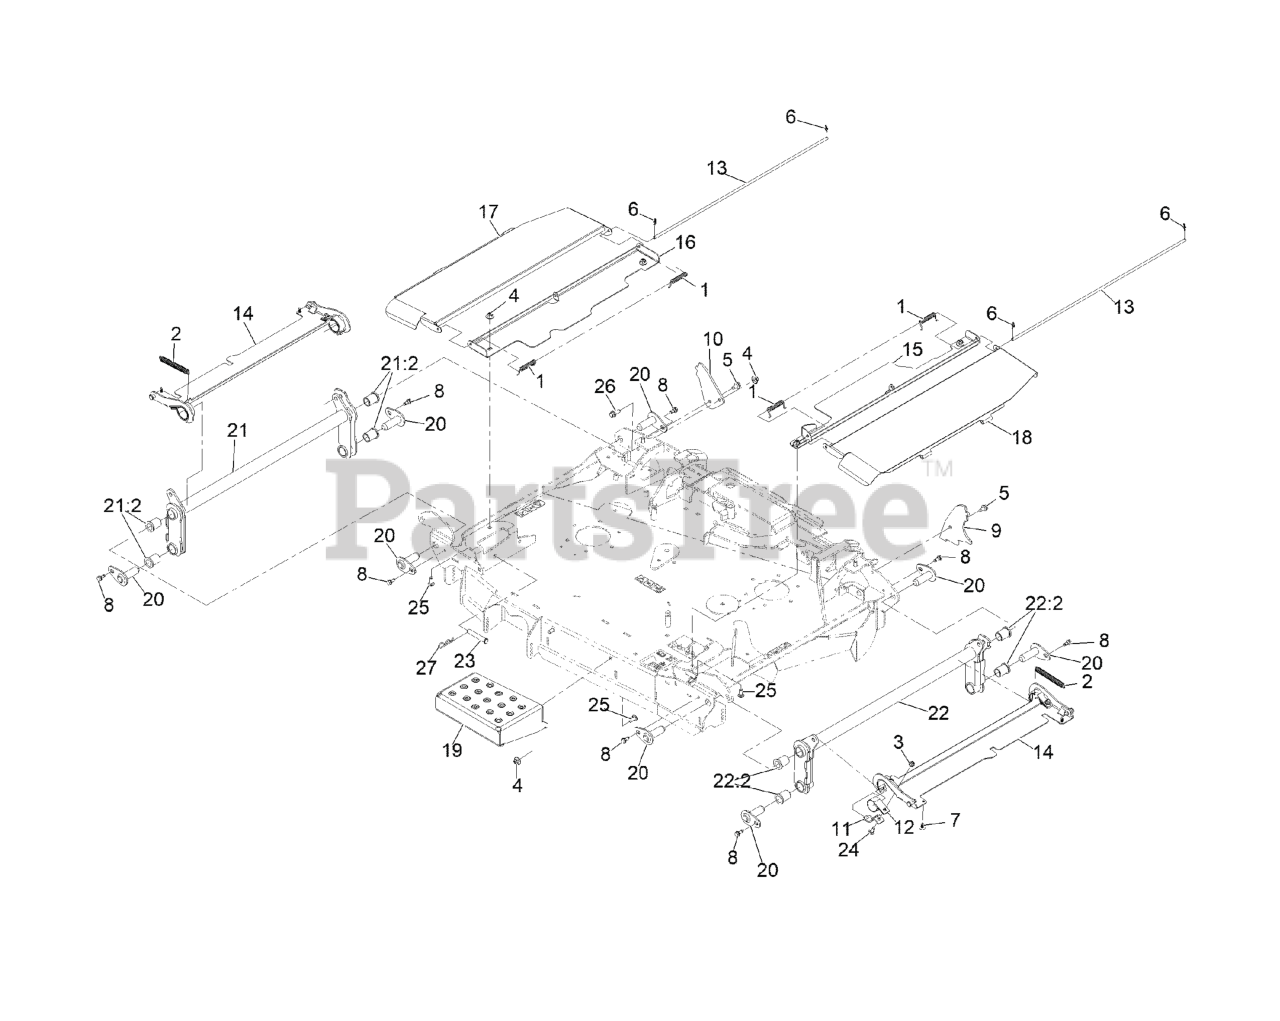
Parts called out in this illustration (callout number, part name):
1	SPRING-TORSION
3	NUT-HF, NI
4	Nut-Nyloc 3/8-16 Flg
5	SCREW-HWH
6	PIN-COTTER, LOCKING
7	PLUG-PLASTIC
8	SCREW-SHOULDER
9	BRACKET-DECK STOP, LH
10	BRACKET-DECK STOP, RH
11	PLATE-RETAINER, BEARING
12	BEARING-STRAP, NYLON
13	COVER-ROD, PIVOT
14	COVER-WING
15	SHIELD-CENTER, LH
16	SHIELD-CENTER, RH
17	Panel-Shield Hinge, LH
18	Shield-Center, RH
19	Panel-Step
20	ASM-DECK PIN
21	ASM-FOLS ARM, RH
21:2	BUSHING-FLANGED
22	ASM-FOLD ARM, LH
22:2	BUSHING-FLANGED
23	PIN-CLEVIS
24	SCREW-CARR
25	BOLT-CARR
26	SCREW-HHF 3/8-16 X 1
27	PIN-HAIR
